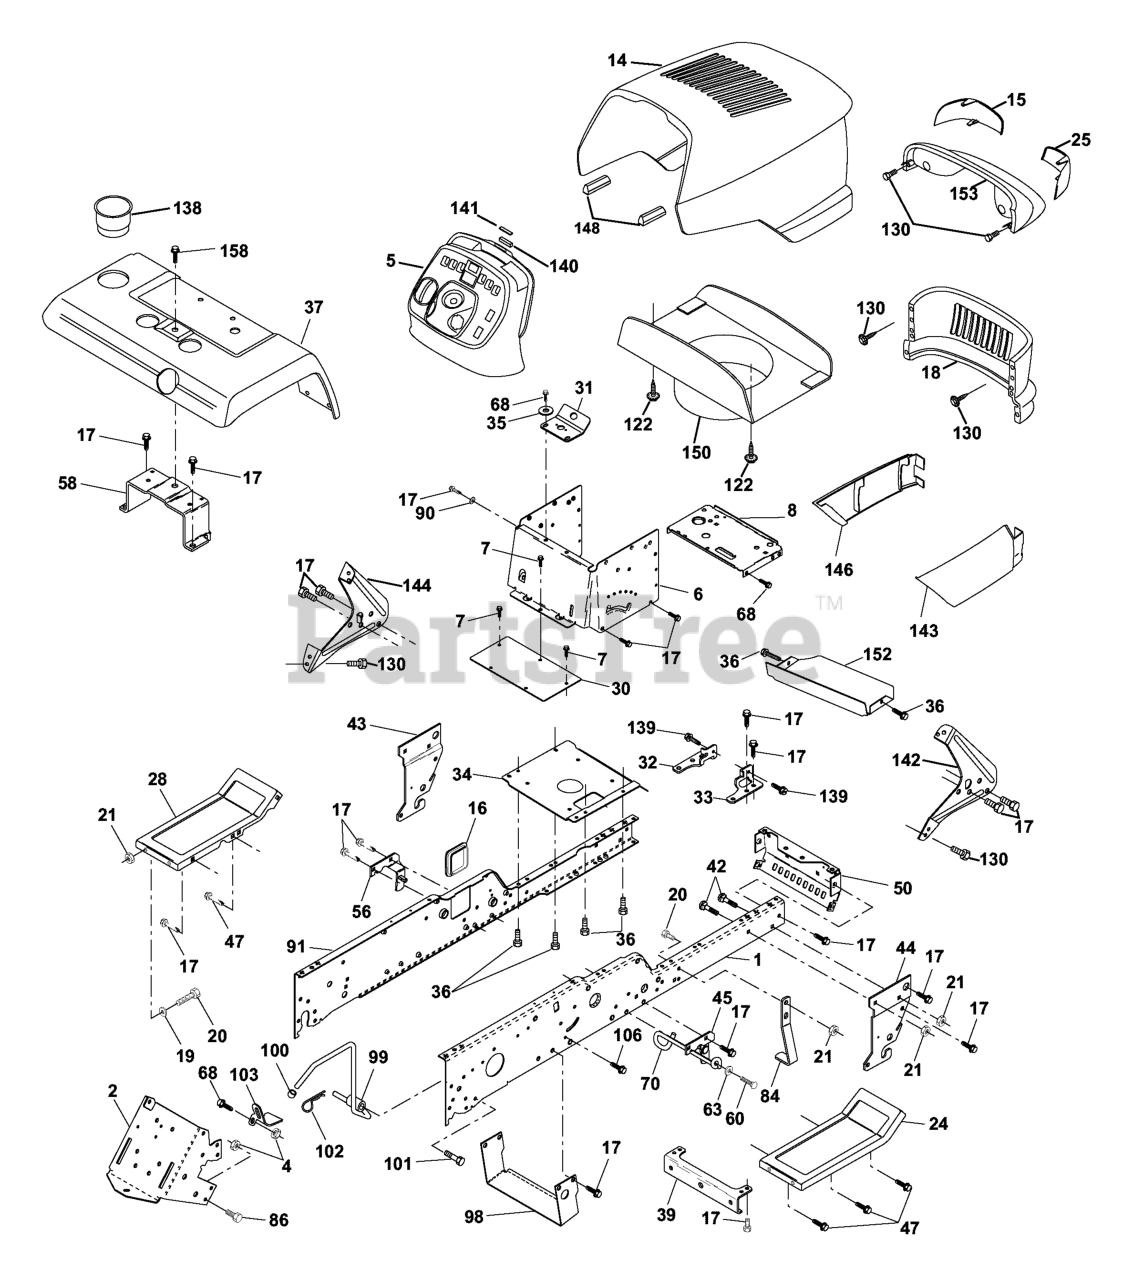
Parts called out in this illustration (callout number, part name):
1	RAIL, FRAME RH
2	DRAWBAR, GT
4	Nut, Lock Hex 7/16 Unc
5	DASH, PLASTIC
6	DASH VGT, LOWER
7	SCREW
8	SUPPORT, BATTERY
14	HOOD ASM,
15	LENS LH
16	COVER ACCESS
17	SCREW 3/8-16X3/4
18	GRILLE
19	WASHER
20	BOLT
24	FOOTREST LT/YT/GT RH
25	LENS RH
28	FOOTREST LT/YT/GT LH
30	SADDLE.HYDRO.95
31	BRACKET SUPT 1-PC VGT STEERING
34	PLATE ASM ENG CHASSIS
35	WASHER
36	SCREW 5/16"
39	BRACKET AXLE, FRONT
42	BOLT D
43	FRONT SUSPENSION BRKT LH
44	FRONT SUSPENSION BRKT RH
45	BRACKET SUSP RH
47	SCREW LT
50	BRACKET, CHASSIS FRONT
56	BRACKET ASM, SUSP CHASSIS
58	BRACKET ASM, FENDER
60	SCREW.3/8-16
63	WASHER
68	Screw, 5/16-18 x 1/2
70	KEEPER, BELT VGT GROUND
84	MOWER STOP
86	BOLT
90	LOCKWASHER
91	RAIL, FRAME LH
98	BRKT, CHASSIS SKID
99	ROD ASMBLY BYPASS
100	PLUNGER CAP
101	SCREW LT
102	RETAINER M
103	BRACKET LOCK BYPASS
106	SCREW
122	SCREW.HEX.WS.HD.8-18 X 7/8
130	SCREW
138	CUPHOLDER
139	BOLT, SHOULDER 5/16-18
140	MAGNET STEALTH
141	STRIKER PLATE
142	BRACKET DASH STEALTH(R)
143	SKIRT, GRILLE RH
144	BRACKET DASH STEALTH LH
146	SKIRT, GRILLE LH
147	SCREW
148	EXTRUSION BUMPER (3 2) (2 2)
150	DUCT HEAT HOOD
152	BROWNING SHIELD
153	LENS ASM HEADLITE DUAL
158	SCREW 3/8-16X1/2
